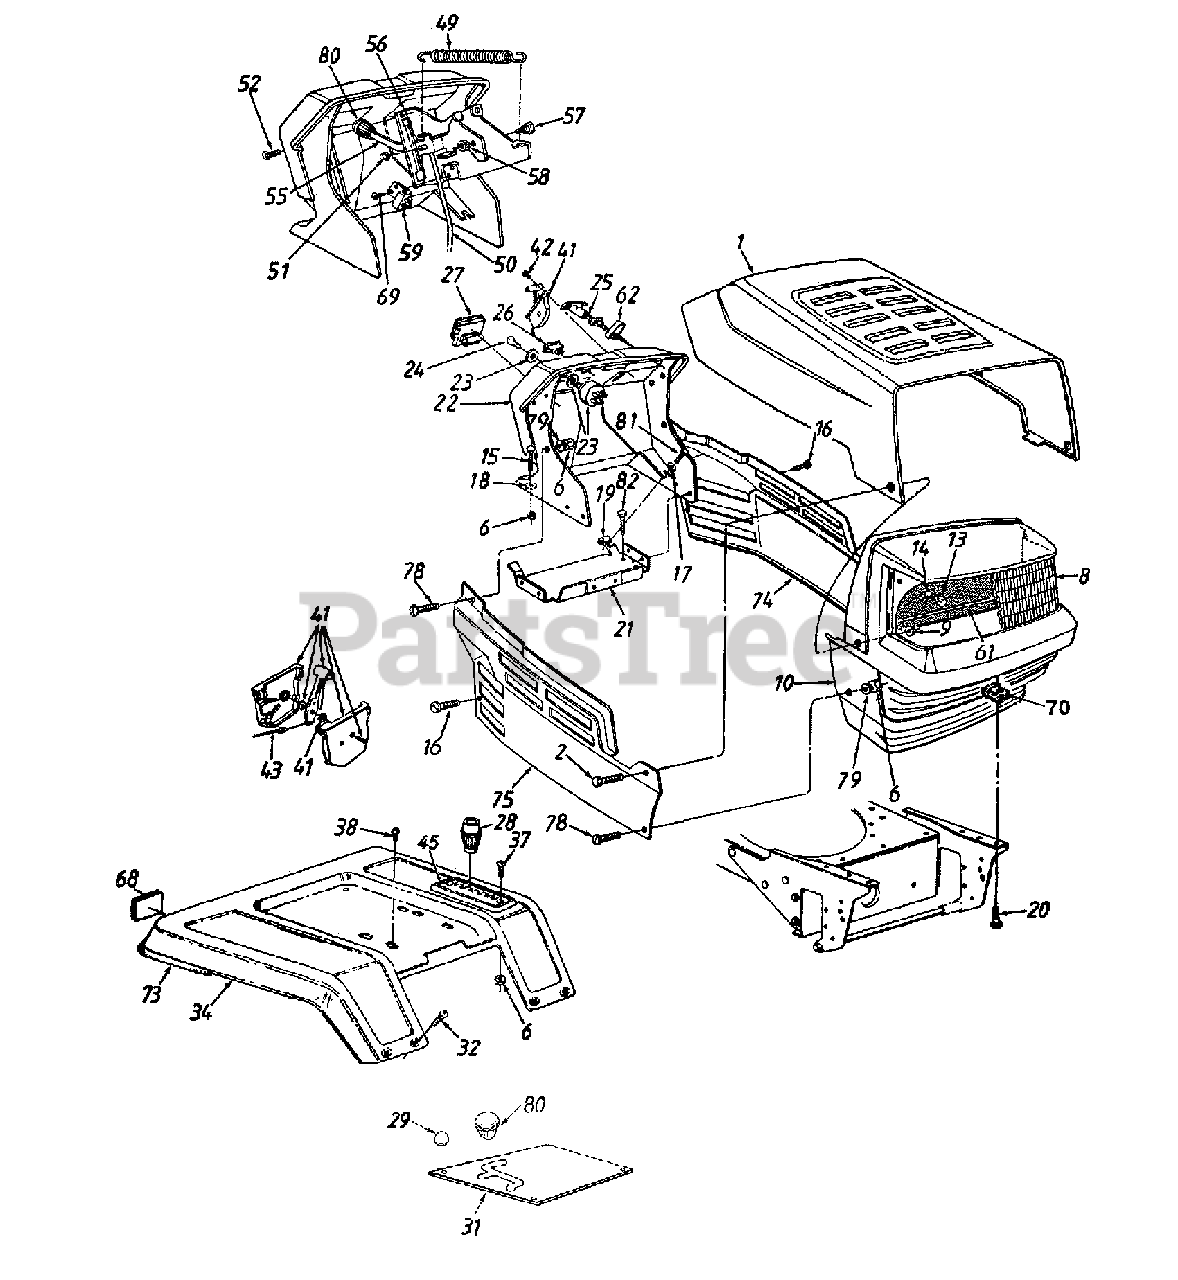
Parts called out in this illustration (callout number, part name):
6	Hex Sems Nut 1/4-20 Thd.
8	Headlight Lens w/Logo
9	Flange L-Nut 1/4-20 Thd.
10	Grille
13	Lamp
14	Socket
15	Carriage Bolt 1/4-20 x 1.0"
16	Hx Wash Hd. TT-Tap Scr. 1/4-20 x .5" L
17	Flat Washer .281" I.D. x .73" O.D.
18	Bolt Retainer 1/4" I.D.
19	Speed Nut 1/4-20 Thd.
20	Hex Bolt 5/16-18 x .75"
23	Ignition Switch
24	Ignition Key
25	Choke Control
27	Ammeter
28	Shift Knob
38	Hx Wash Hd. AB-Tap Scr. 5/16 x .75" L
41	Throttle Box Assembly
42	Truss Mach. AB-Tap Scr. #10 x .5"
43	Throttle Control Wire 35"
45	6-Speed Selector Plate (825)
49	Ext. Spring 5.06"
50	Deck Control Rod
51	Speed Nut 1/4" Rod
52	Torx Mach. Scr. 1/4 x .62"
55	PTO Lever
58	Hex L-Nut 5/16-18 Thd.
59	Safety Switch
61	Grille Reflector Label
62	Retainer Clip
68	Reflector
69	Hx Washer Hd. B-Tap Scr. #10 x .38"
70	U-Nut 5/16-18 Thd.
73	Trim Strip 81"
79	Bell Washer 1/4" I.D.
80	Small Shift Knob
81	Hex TT-Tap Scr. 1/4-20 x .75"
82	Hex AB-Tap Scr. 1/4 x .62"
